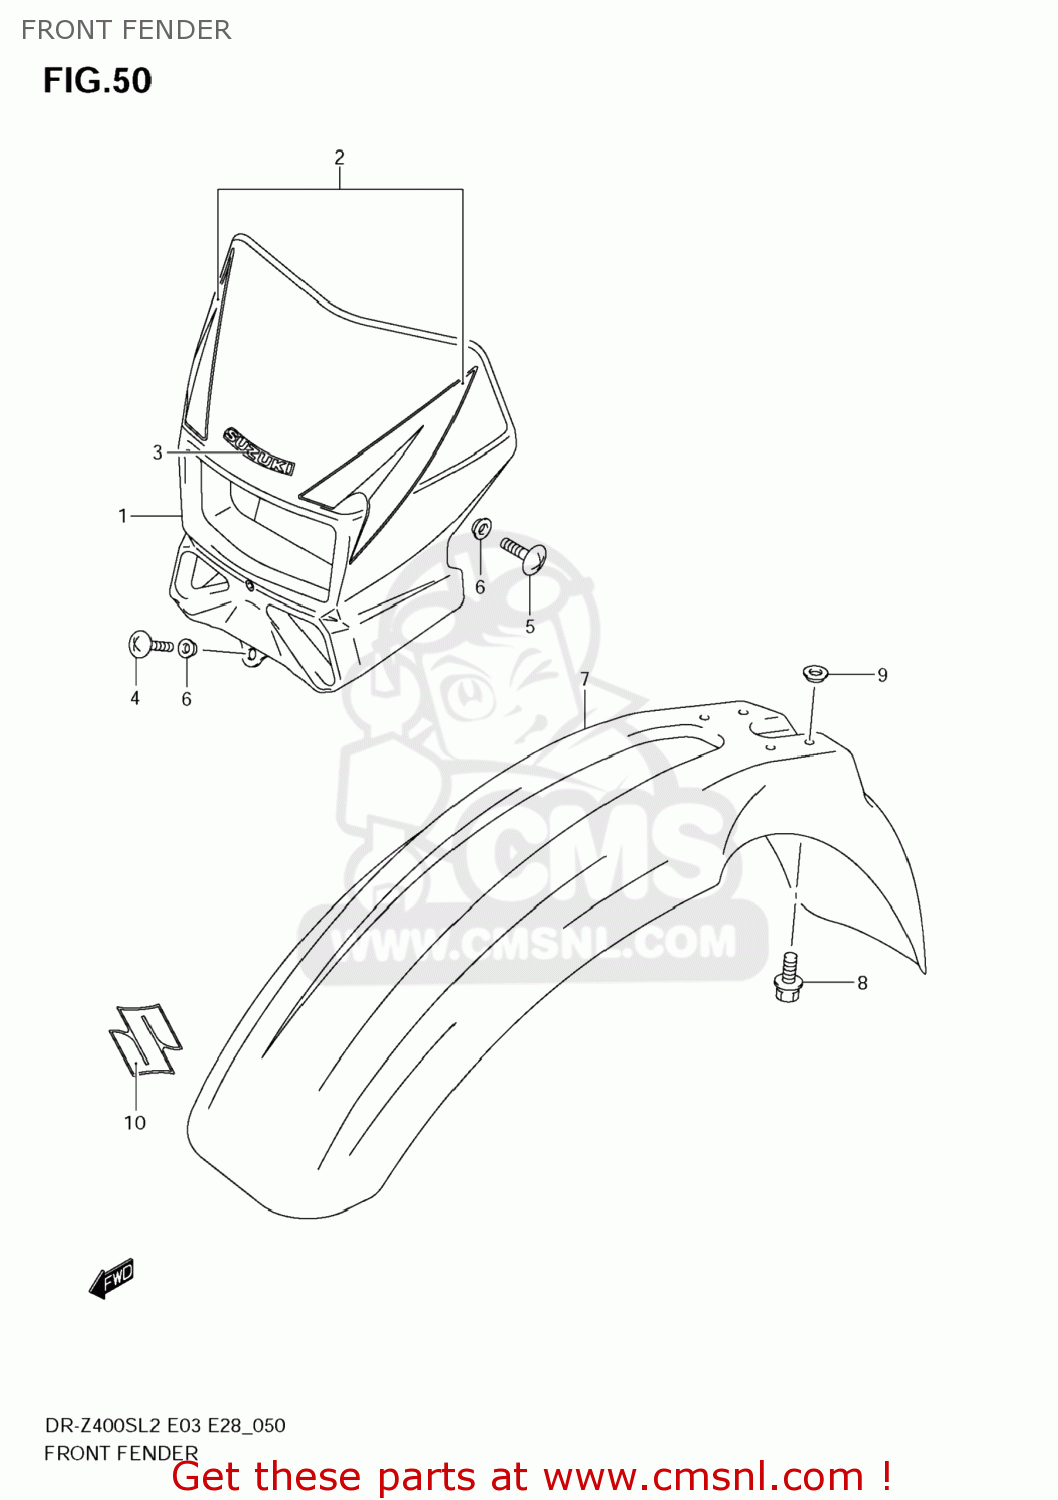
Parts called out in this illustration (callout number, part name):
1	COVER,HEADLAMP
2	TAPE SET,HEADLAMP HOUSING
3	EMBLEM,SUZUKI
4	SCREW
5	SCREW
6	WASHER
7	FENDER,FR
8	BOLT(6X16)
9	WASHER
10	EMBLEM,S
